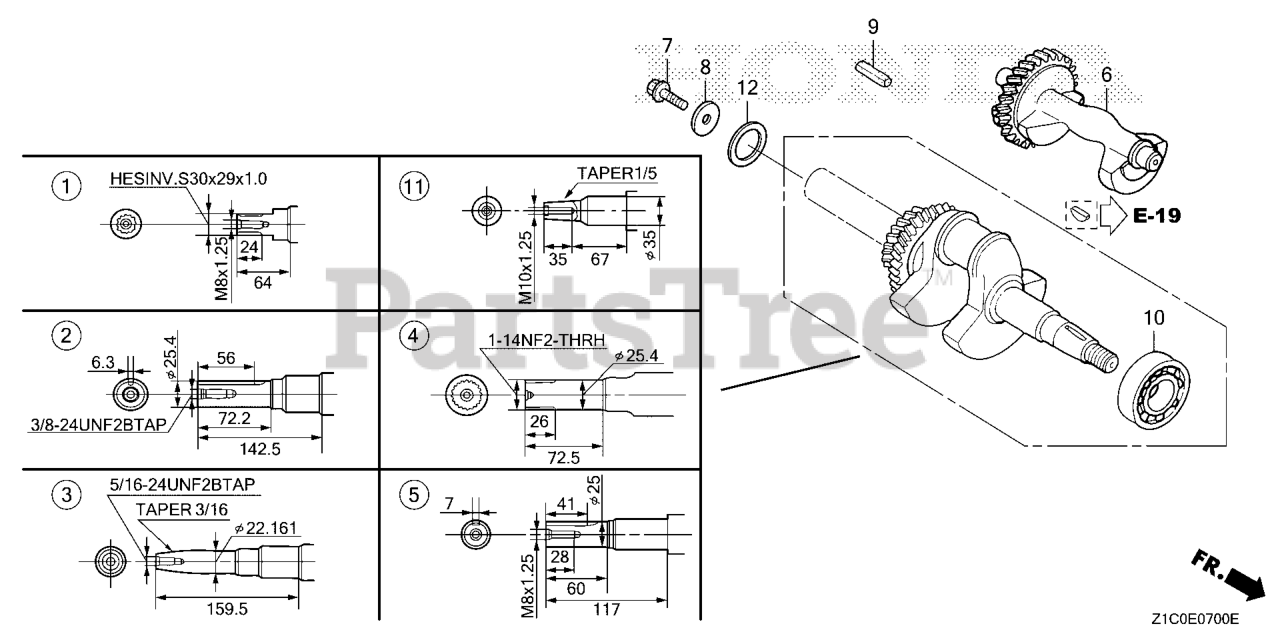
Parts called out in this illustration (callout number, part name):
2	CRANKSHAFT
6	WEIGHT, BALANCER
9	KEY (6.3X6.3X43)
10	BEARING, RADIAL BALL (6207SH)
12	WASHER, THRUST (35MM) (NOT AVAILABLE)
